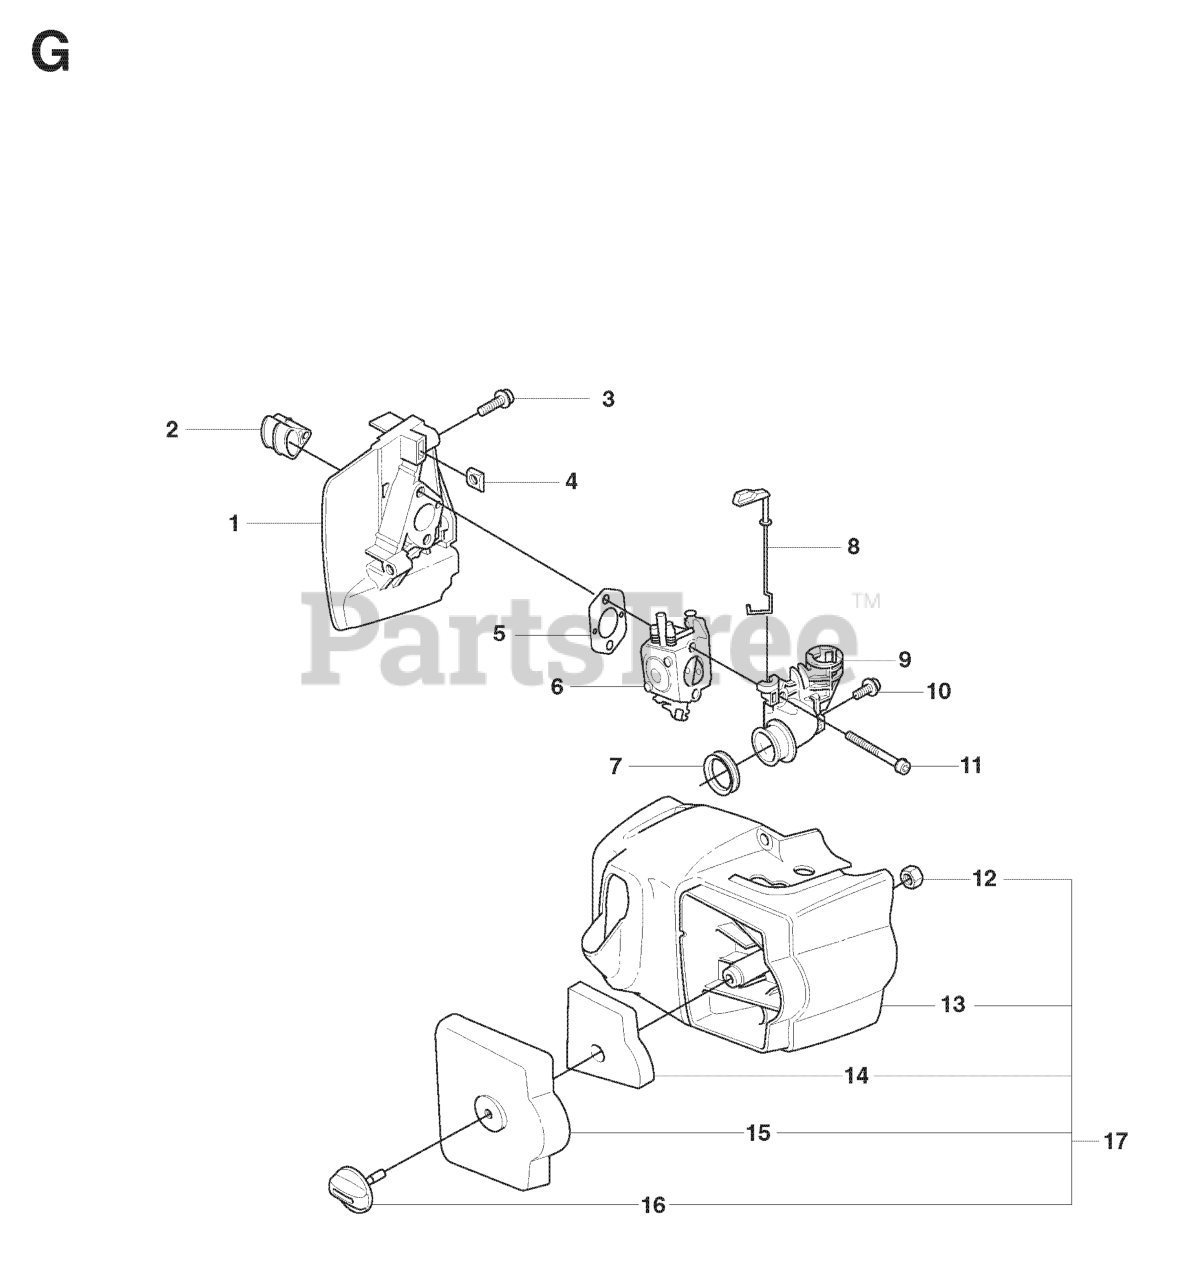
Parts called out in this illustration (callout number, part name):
3	SCREW
6	CARBURETOR
8	CHOKE CONTROL
14	AIR FILTER
15	AIR FILTER COVER
17	CYLINDER COVER ASSY 325
